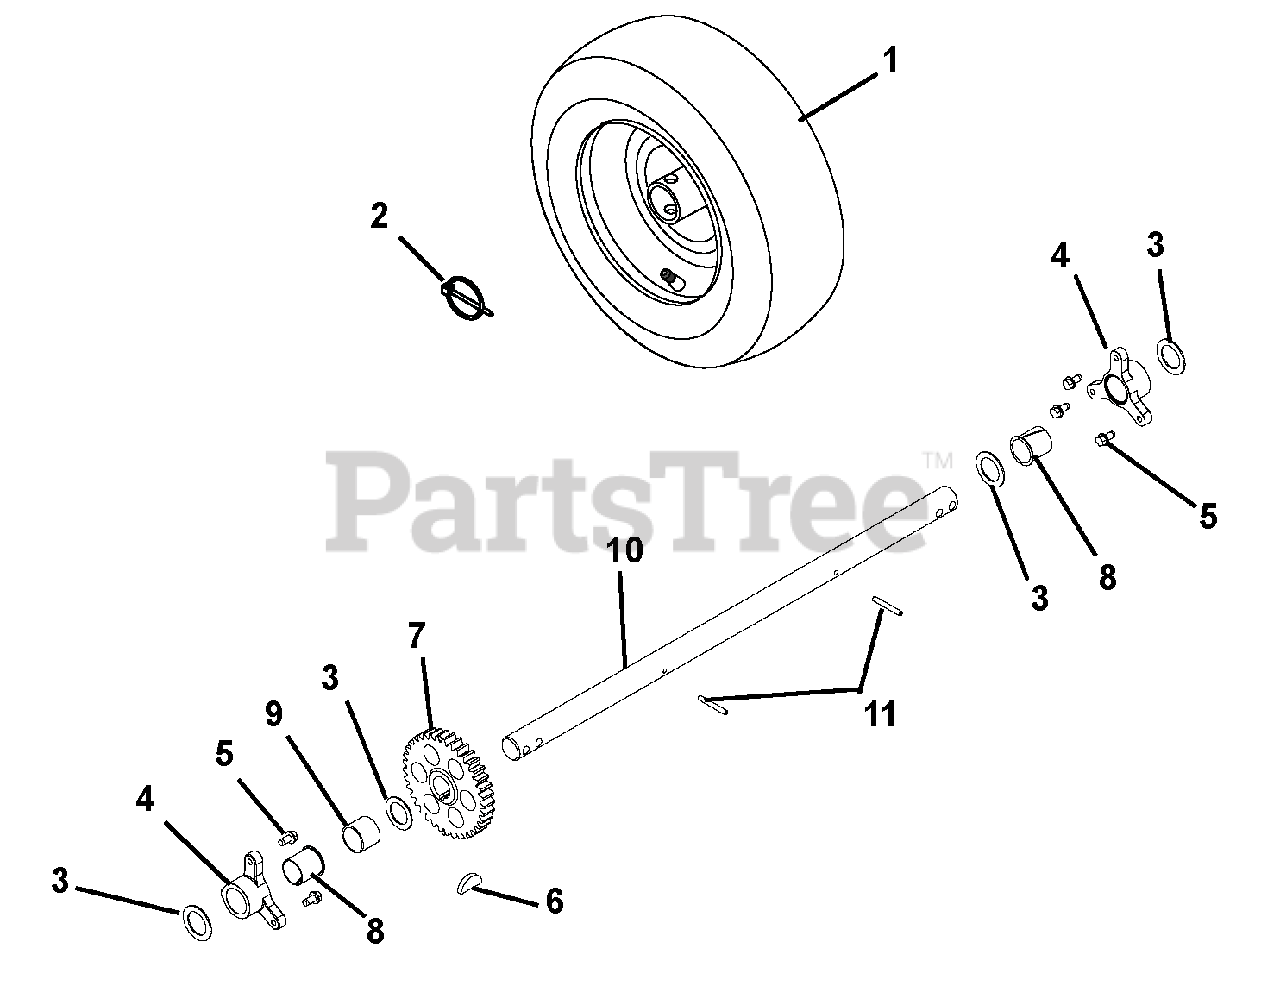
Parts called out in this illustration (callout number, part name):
1	TIRE/WHEEL, RH 15X5.00-6 PIN
2	PIN-LOK .31X2.00
3	WSHR-FL-STL 1.010X1.505X.062YZ
4	BUSHING, RAKE SHAFT 1"
5	SCR-TAP .25-20X.50 HWH TR YWZ
6	KEY-WDRF .25X.750X.313 SAE91
7	GEAR, SPUR
8	BSHG-FLG SPLIT NYLINER 1.0" HP
9	BSHG-SLV, 1.012X1.125X1.00
10	AXLE, 1.00" SOLID
11	PIN-ROLL .188X1.25
